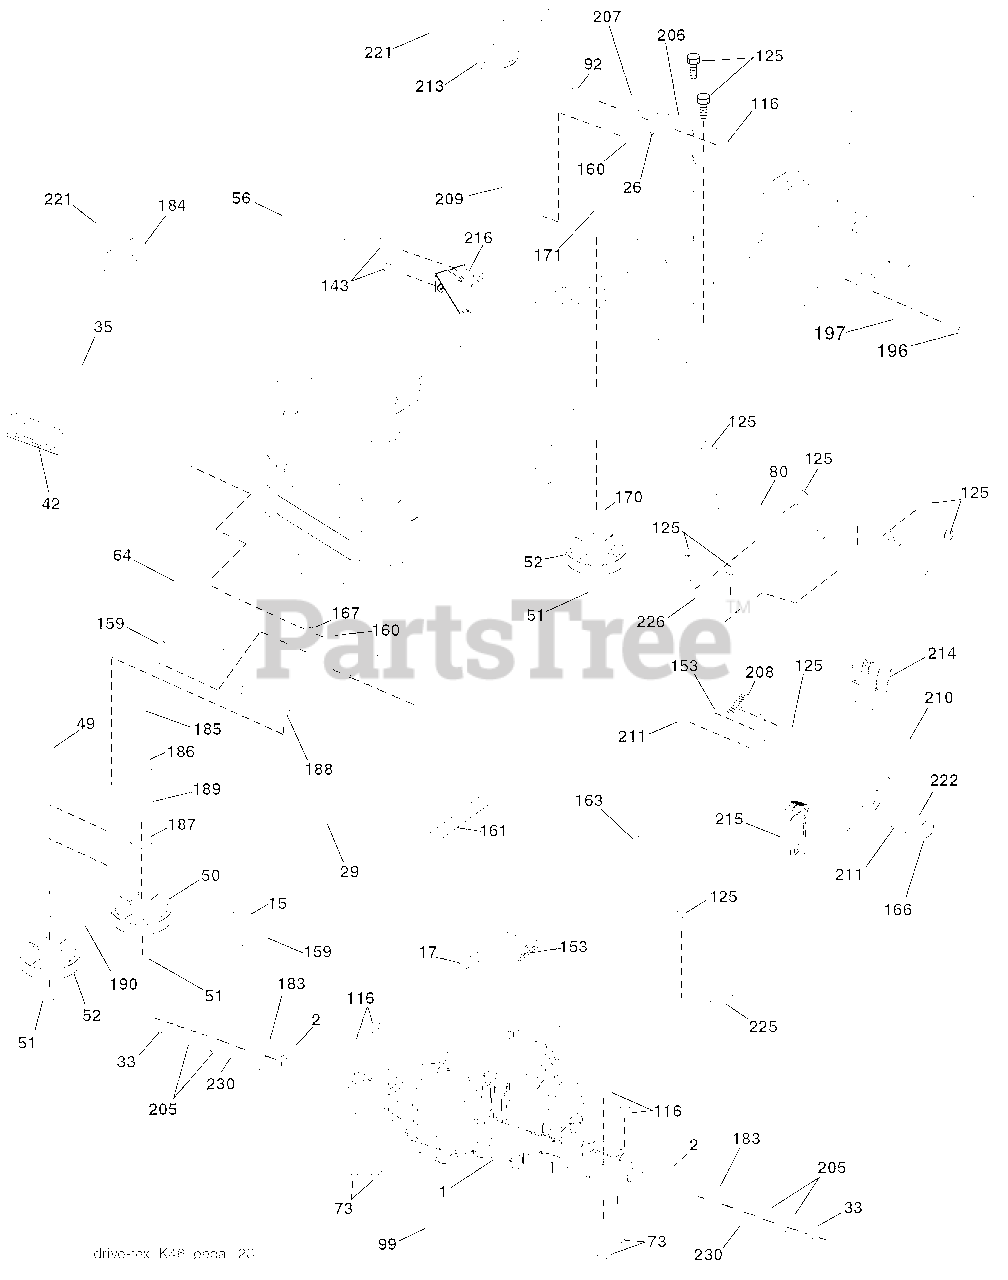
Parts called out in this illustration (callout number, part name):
2	Key
15	Washer 13/32 x 13/16 x 16 Ga.
17	Spring, Brake
26	Spring Return Cruise
29	Rod, Brake
33	Ring E
35	Rod, Brake, Park
42	Cover, Foot Pedal
49	Bolt
50	Pulley Idler Flat
51	Lock Nut 3/8-16
52	Idler V-Groove 910" Offset
56	V-Belt, Drive
64	Shaft Asm. Pedal Brake Control
73	Bolt Hex 5/16-18 x 3.75
80	Strap Torque
92	Bolt Fin Hex 5/16-18 unc x 1.25
99	Rod Spring Bypass
116	Nut Lock Hex Flange 5/16-18
125	Screw 5/16-18 x 3/4
143	Screw 5/16-18 x 1/2
153	Retainer Spring
159	Pin Cotter 1/8 x 3/4
160	Retainer Clip
161	Spring, Return, Clutch
163	Rod Pedal Control
166	Nut Push .625
167	Latch Brake Parking
170	Keeper Belt Centerspan
171	Bolt
183	Spacer Axle
184	Handle Parking Brake
185	Bolt
186	Spacer Retainer
187	Washer
188	Link Clutch Ground Drive
189	Bellcrank Ground Drive
190	Keeper Bellcrank Ground Drive
196	Screw 3/8-16 x 1
197	Link Clutch Anti-Rotation
205	Washer 25/32 x 1-5/8 x 16 Ga.
206	Bracket Mount Latch Cruise
207	Latch Control Cruise
208	Gear Sector Control Cruise
209	Rod Control Cruise
210	Rockr Asm. Pdeal Control
211	Bearing Nylon
213	Knob control Cruise
214	Pad Pedal Forward
215	Pad Pedal Reverse
216	Bracket Pulley Idler
221	Retainer Spring Clip Handle
222	Washer 21/32 x 1-1/4 10 Ga.
225	Keeper Belt Transaxle
226	Bracket Mount Torque
230	Washer Harden .793 x 1.637 x 060
